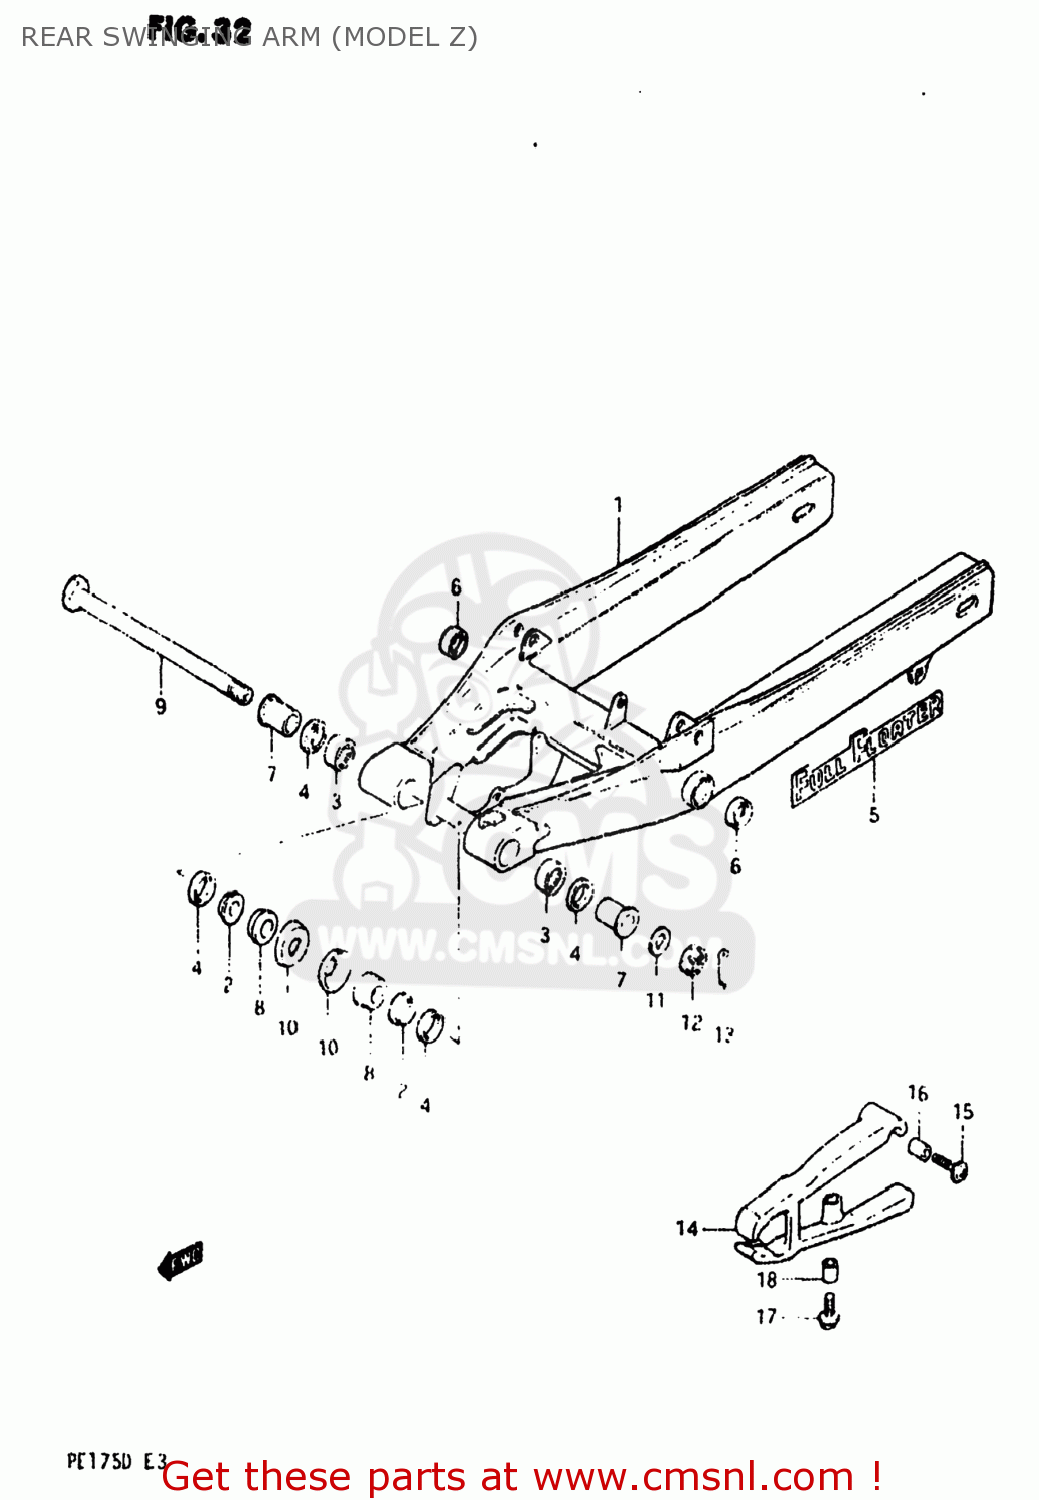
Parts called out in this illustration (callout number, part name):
1	SWING ARM ASSEMBLY,REAR
2	BUSH,RR SWINGINGARM PIVOT
3	BEARING(20X27X20)
4	OIL SEAL
5	EMBLEM,SWING ARM
6	OIL SEAL
7	SPACER,RR SWGARM PIVOT
8	SPACER,RR SWGARM PIVOT INNER
9	SHAFT,RR SWINGINGARM PIVOT
10	COVER,RR SWGARM DUST SEAL
11	WASHER
12	NUT 14MM
13	COTTER PIN
14	BUFFER,CHAIN TOUCH DEFENSE
15	BOLT,CHAIN TOUCH DEFEND
16	SPACER (6.1X9X9)
17	BOLT,CHAIN TOUCH DEFEND
18	SPACER(6.5X10.5X22.5)
